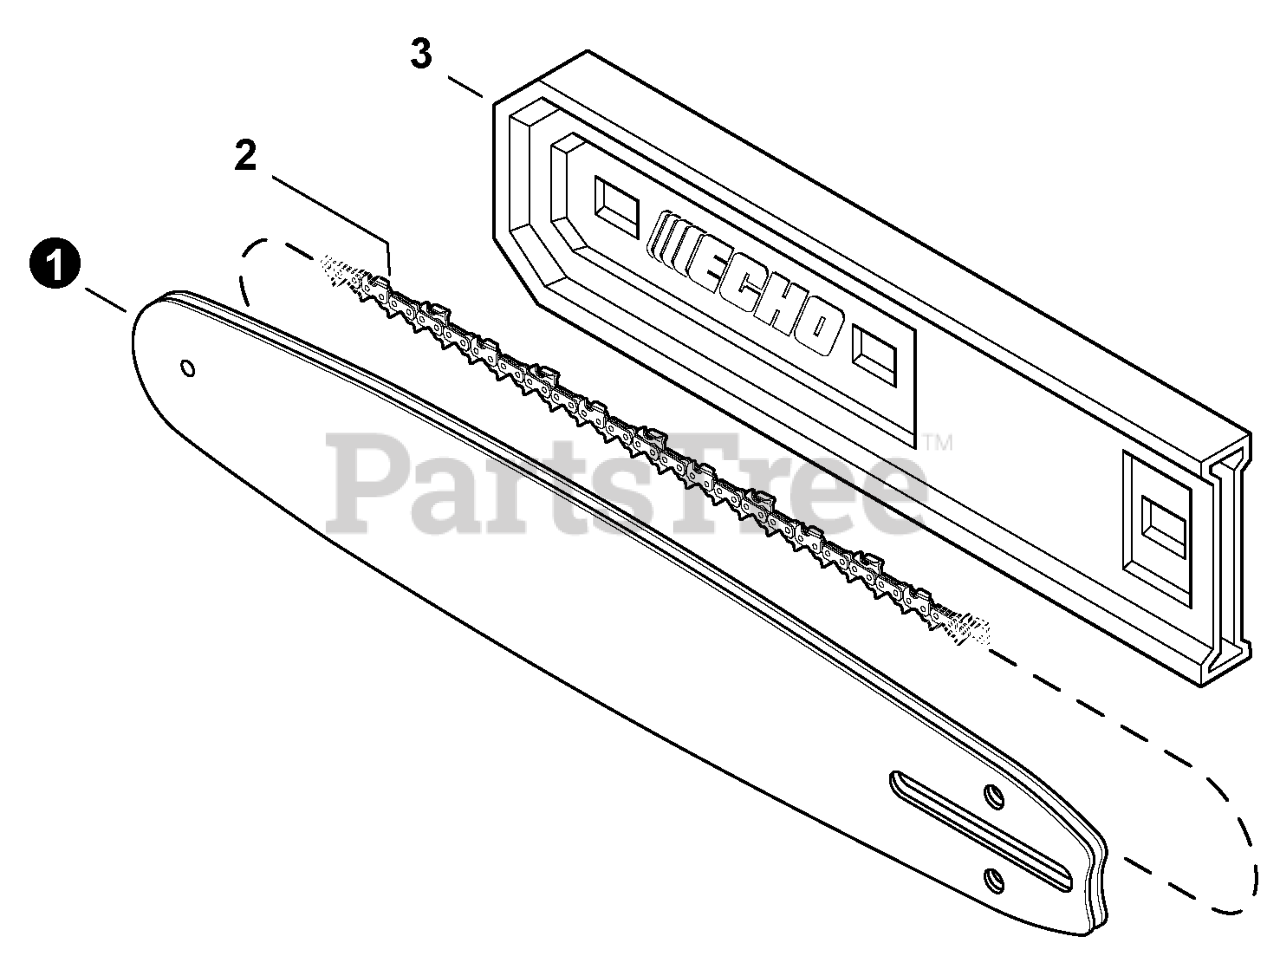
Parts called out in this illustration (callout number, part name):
1A	GUIDE BAR, 10" 0.050" GA
1B	GUIDE BAR, 10" 0.043" GA
1C	GUIDE BAR, 12" 0.050" GA
1D	GUIDE BAR, 12" 0.043" GA
2A	SAW CHAIN 10" 0.050" GA
2B	SAW CHAIN 10" 0.043" GA
2C	SAW CHAIN 12" 0.050" GA
2D	SAW CHAIN 12" 0.043" GA
3	SCABBARD 10"
3	SCABBARD 12"
